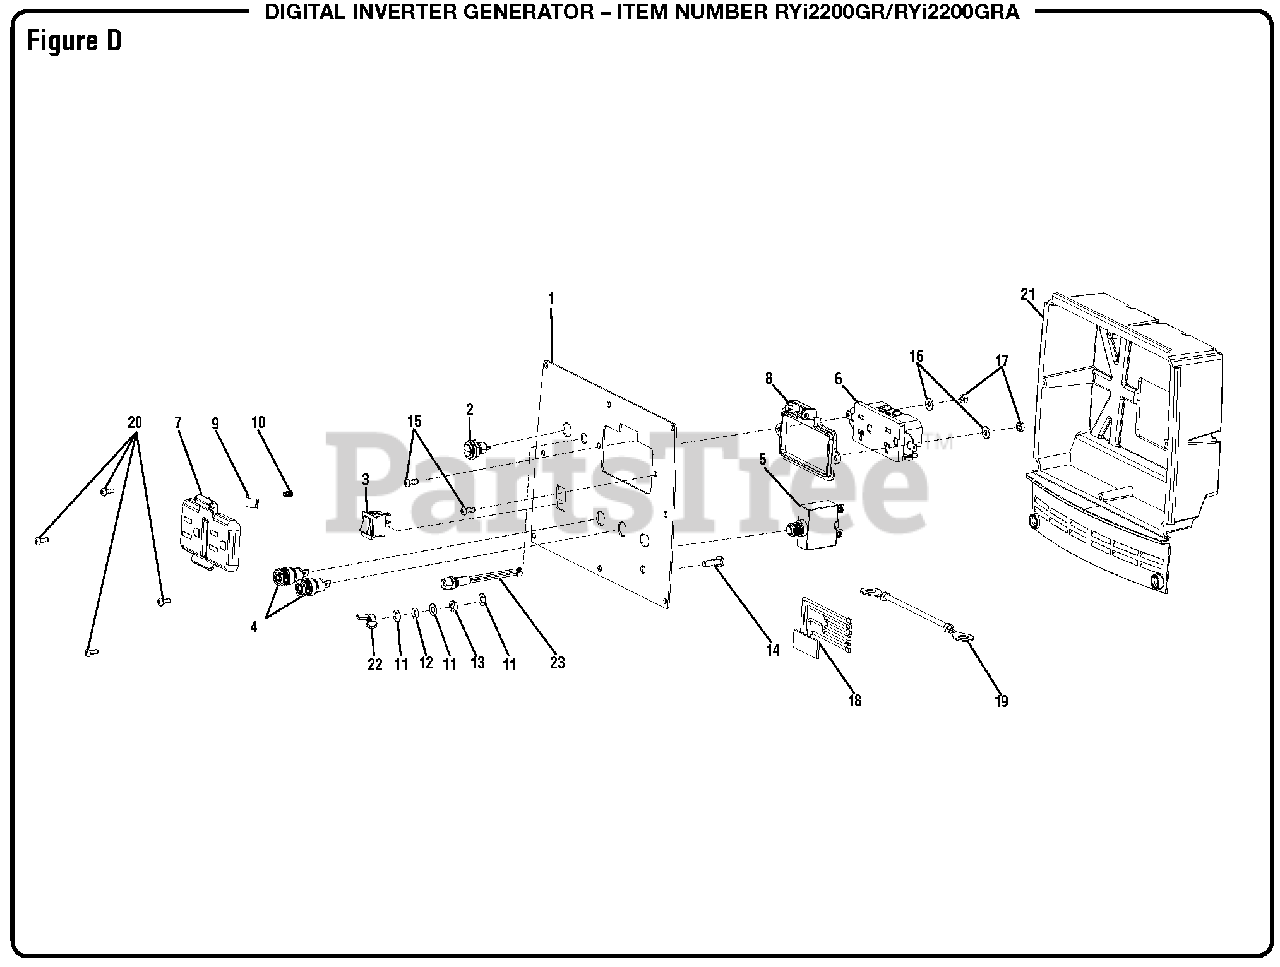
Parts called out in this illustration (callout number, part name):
1	Front Cover
2	Reset Button
3	Auto Idle Switch
4	Connector (Black)
5	Circuit Breaker (20A)
6	120 Volt Duplex Receptacle (20 Amp)
7	Receptacle Cover (Front)
8	Receptacle Cover
11	Flat Washer (OD10 x ID5.3 x 0.5t)
12	Lock Washer (OD9 x ID5 x 1.3t)
13	Hex Nut (M5)
14	Bolt (M5 x 16 mm, Pan Hd.)
15	Bolt (M4 x 10 mm, T15 Torx Hd.)
16	Washer (OD10 x 4.2 x 1t)
17	Hex Nut (M4)
18	Internal Wire Assembly
19	Ground Wire
20	Screw (M6-20 x 0.38 mm, T15 Torx Pan HD.)
21	Electrical Panel Housing
22	Wing Nut (M5)
23	Indicator (Red LED 3.3V-4mA)
